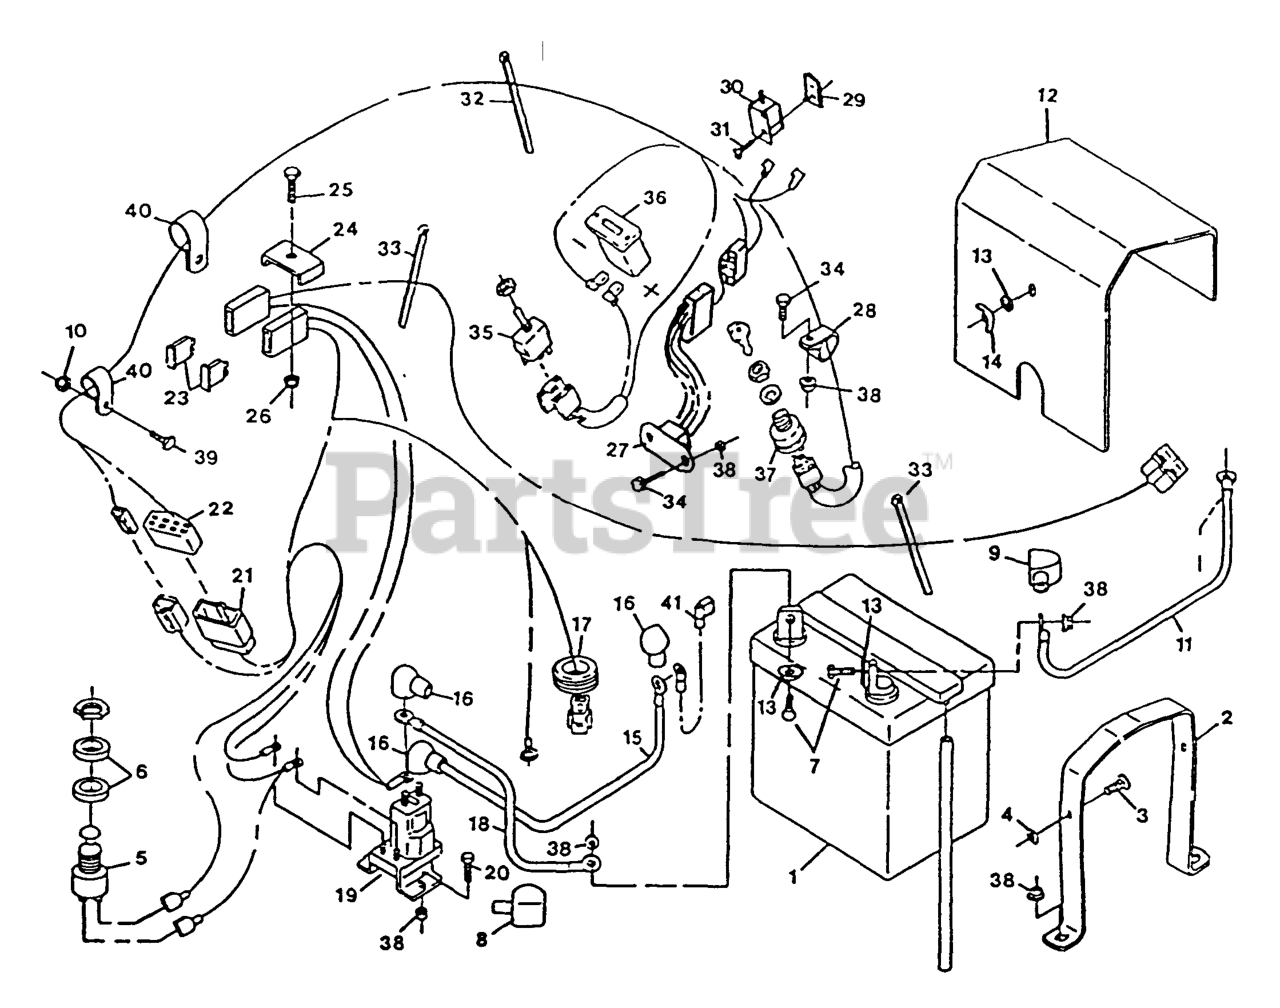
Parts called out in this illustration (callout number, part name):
1	Battery, 12v Manifold
2	STRAP,BATTERY HOLDDOWN
3	BOLT-CARR
4	NUT-RETAINING
5	SWITCH,PUSH BUTTON
9	INSULATOR, BATTERY -
11	WIRE-GROUND
14	NUT-WING
16	INSULATOR-SOLENOID
17	GROMMET
21	HARNESS,WIRING HYDRO
23	FUSE-BLADE TYPE, 20 AMP
24	CLIP-FUSE BLOCK PLTD
27	MODULE-OPC NO TIME DELAY
28	CLIP-LOOM
29	PLATE-TAPPED
30	SWITCH-OPEN, NORMALLY
32	TIE-PLASTIC
33	TIE-CABLE
35	SWITCH,W/TERM CLIPPD
36	METER-HOUR
37	SWITCH,IGNITION
40	CLIP-LOOM
